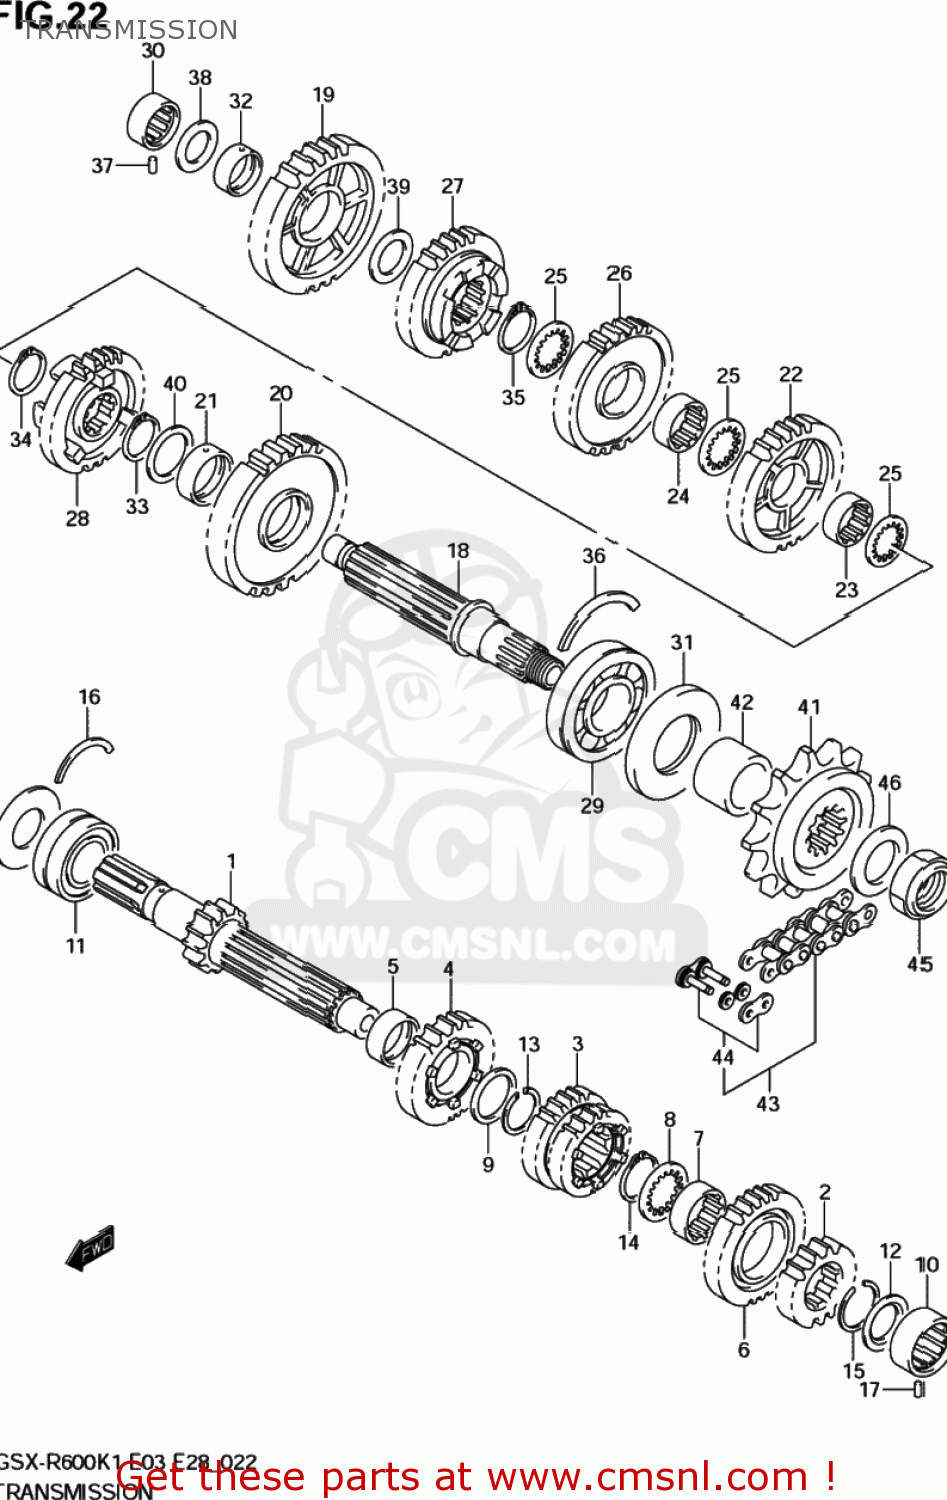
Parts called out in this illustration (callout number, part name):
1	SHAFT,COUNTER
2	GEAR,2ND DRIVE
3	GEAR,3RD & 4TH DRIVE
4	GEAR,5TH DRIVE(NT:24)
5	BUSH,5TH DRIVE GEAR
6	GEAR,6TH DRIVE(NT:23)
7	BUSH,6TH DRIVE GEAR
8	WASHER,LOCK
9	SHIM(27X36X2.5)
10	BEARING(20X34X13.5)
11	BEARING(25X52X20.6)
12	SEAL,OIL(20X31.2X2.7)
13	CIRCLIP
14	CIRCLIP
15	CIRCLIP
16	C RING
17	PIN(6X10)
18	SHAFT,DRIVE
19	GEAR,FIRST DRIVEN
20	GEAR,2ND DRIVE
21	BUSH,2ND DRIVEN GEAR
22	GEAR,3RD DRIVEN(NT:32)
23	BUSH,3RD DRIVEN GEAR
24	BUSH,3RD DRIVEN GEAR
25	WASHER,3RD & 4TH DRIVEN
26	GEAR,4TH DRIVEN
27	GEAR,5TH DRIVEN(NT:29)
28	GEAR,6TH DRIVEN(NT:25)
29	BEARING(28X70X18)
30	BEARING(20X34X13.5)
31	SEAL,OIL(34.8X70X6)
32	BUSH(22X26X9)
33	CIRCLIP
34	CIRCLIP
35	CIRCLIP
36	C RING
37	PIN(6X10)
38	SHIM(20X34X1)
39	SHIM(22X34X1)
40	WASHER(27X36X1)
41	SPROCKET,ENGINE(16T)
42	SPACER,ENGINE SPROCKET
43	CHAIN ASSY,DRI
44	JOINT SET
45	NUT
46	WASHER(25X41X3)
